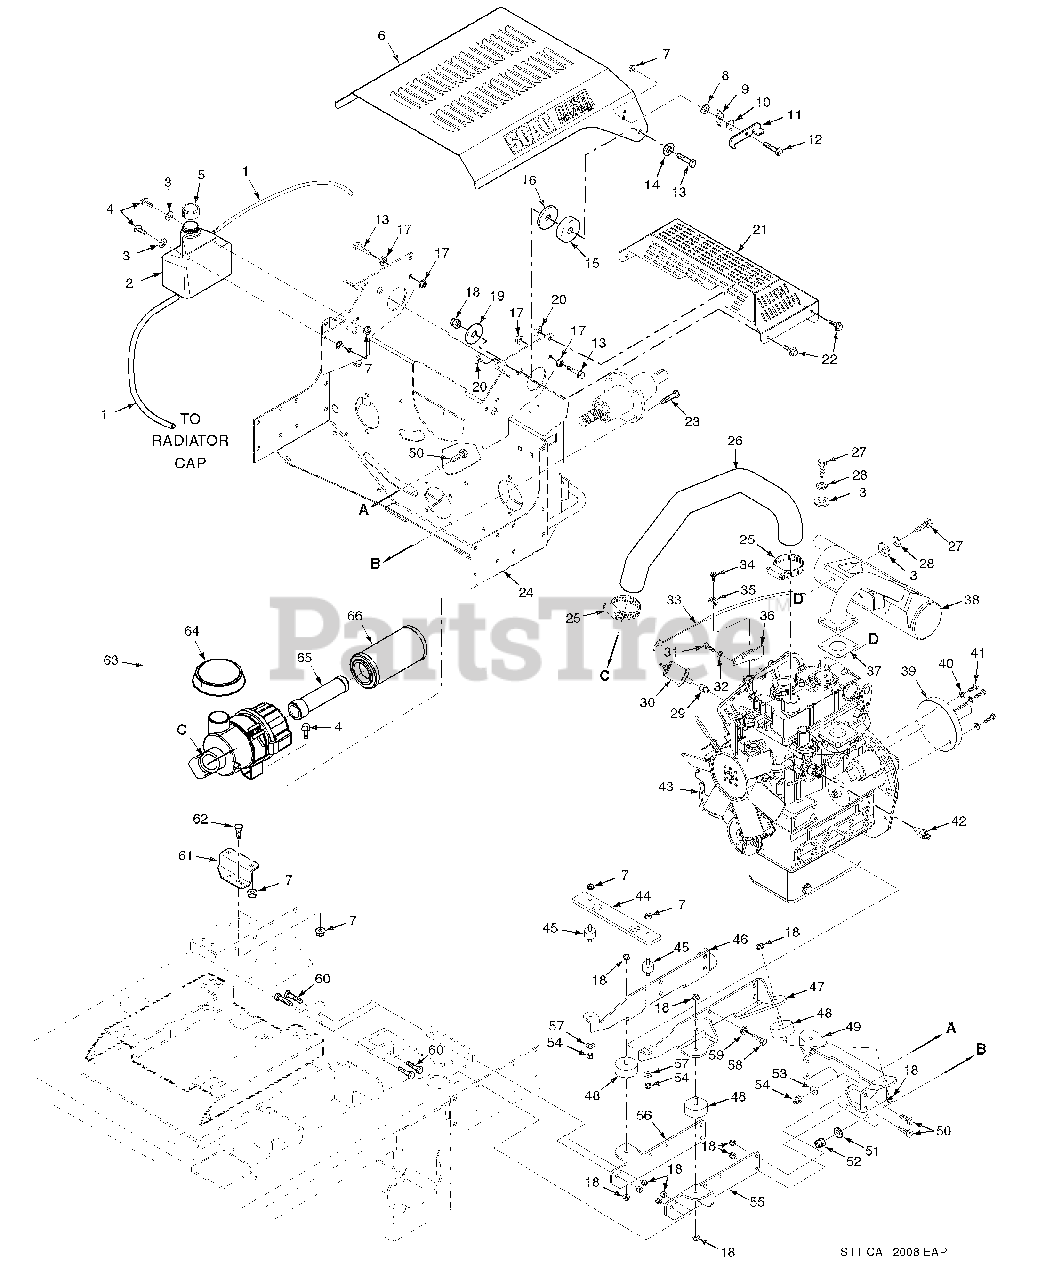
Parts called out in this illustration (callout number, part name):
1	Hose, Coolant Resrvoir Bottle
2	Coolant Reservoir Bottle
3	Flatwasher, SAE 5/16-.344 x .688 x .065
4	Bolt, Hex Head Serr. Flng 5/16-18 x 3/4”
5	Cap, Coolant Reservoir Bottle
6	Hood Assembly w/Decals
7	Nut, Serrated Flange 5/16-18
8	Flatwasher, 3/8-.406 x .812 x .065
9	Lock, Hood Latch
10	Spring, Hood Latch
11	Latch, Hood
12	Bolt, Shoulder 5/16-18 x 1/2”
13	Bolt, Hex Head 3/8-16 x 1-3/4”
14	Flatwasher, 3/8-.391 x .938 x .105
15	Spacer, Hood
16	Disc, Anti Friction
17	Nut, Serrated Flange 3/8-16
18	Nut, Elastic Stop 3/8-16
19	Flatwasher, 3/8-.406 x 1.50 x 7 Gauge
20	U-Nut, 1/4”-20
21	Muffer Guard
22	Bolt, Hex Head Serrated Flange, 1/4-20 x 3/4”
23	Bolt, Hex Head 5/16-18 x 1-3/4” Grd 8
24	Pump Mounting Plate Weldment
25	Clamp, 2-1/4” Max. Dia.
26	Hose, Air Intake
27	Bolt, Hex Head M8-1.25 x 20
28	Lockwasher, 5/16” Spring
29	Elbow, 45 Degree
30	Oil Pressure Sender
31	Bolt, Hex Head M6-1.0 x 16
32	Lockwasher, 1/4” Spring
33	Throttle Cable
34	Screw, Self Tapping
35	Clamp
36	Mounting Bracket, Throttle Cable
37	Muffer, Cat Diesel
38	Gasket, Muffer
39	Stub Shaft
40	Lockwasher, 7/16” Spring
41	Bolt, Hex Head M10 x 1.5 x 35
42	Temperature Sensor, Engine Coolant
44	Mount, Radiator
45	Mount, Radiator Isolation
46	Mounting Bracket Weldment RH
47	Mounting Bracket Weldment LH
48	Mount, Engine Isolation
49	Plate, Rear Engine Mount
50	Bolt, Hex Head 3/8-16 x 1”
51	Flatwasher, 5/16”
52	Nut, Elastic Stop 5/16-18 Grade 8
53	Lockwasher, 3/8” Spring
54	Nut, Elastic Stop 3/8-16
55	Plate, Engine Mount LH
56	Plate, Engine Mount RH
57	Flatwasher, 3/8”
58	Bolt, Hex Head M12-1.25 X 25mm
59	Lockwasher, 1/2” Spring
60	Bolt, Hex Head 3/8-16 x 1”
61	Bracket, Air Cleaner Mount
62	Bolt, Carriage 5/16-18 x 3/4”
63	Air Filter Assembly
64	Rain Cap
65	Air Filter, Inner
66	Air Filter, Outer
